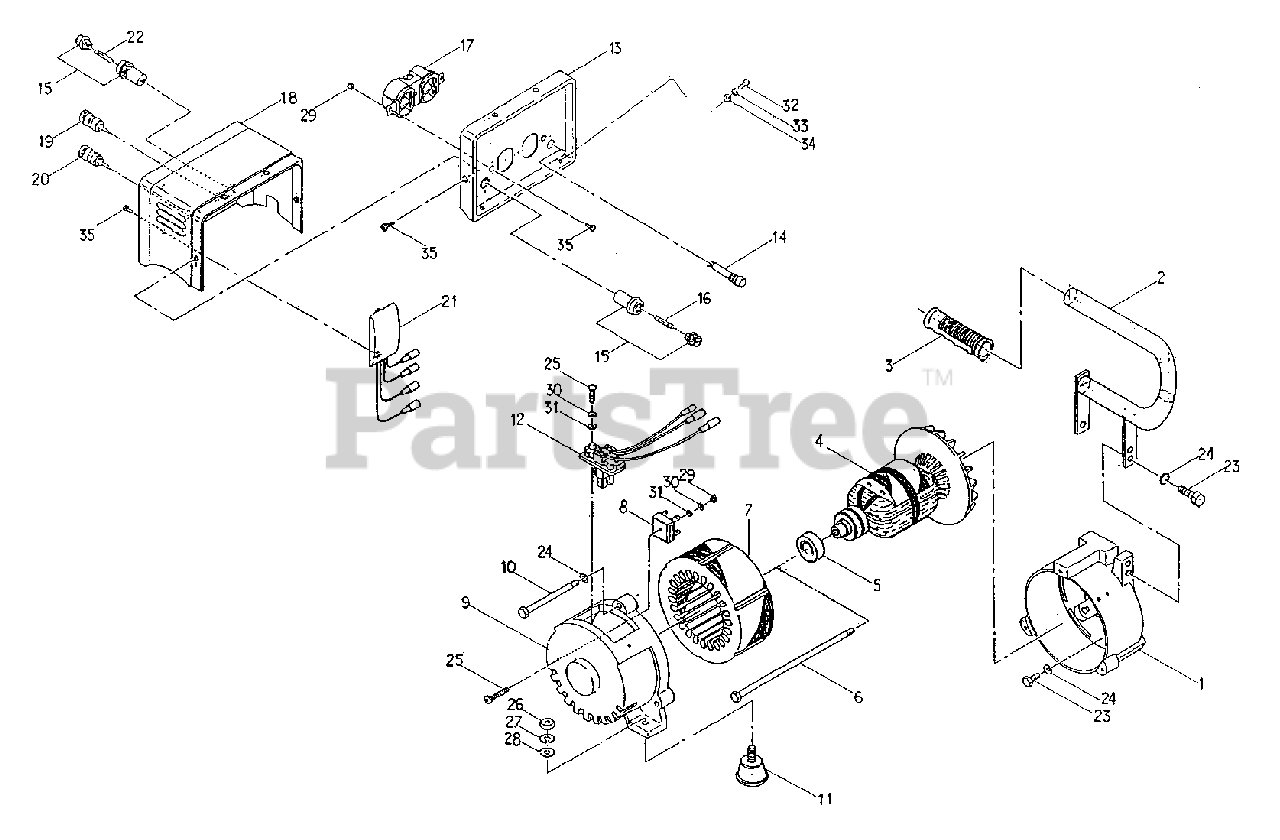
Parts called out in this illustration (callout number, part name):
1	BRACKET - FRONT
2	HANDLE
3	GRIP
4	ROTOR ASSY
5	BEARING, BALL
6	THRU BOLT
7	STATOR ASSY
8	BLOCK, DIODE
9	BRACKET - REAR
10	BOLT, BRACKET
11	RUBBER MOUNT UNIT
12	BRUSH HOLDER ASSY
13	PANEL A
14	NEON LAMP - 110V
15	HOLDER, FUSE
16	FUSE
17	OUTLET - 125V 15A
18	CONTROL BOX ASSY
19	OUTPUT TERMINAL - BLACK
20	OUTPUT TERMINAL - RED
21	AVR UNIT
22	FUSE
23	BOLT - 6X15
24	LOCKWASHER - 6
25	SCREW - 4X25
26	NUT - 8
27	LOCKWASHER - 8
28	WASHER - 8
29	NUT - 4
30	LOCKWASHER - 4
31	WASHER - 4
32	BOLT - 5X15
33	LOCKWASHER - 5
34	WASHER - 5
35	SCREW - 4X10 -- TAPPING
